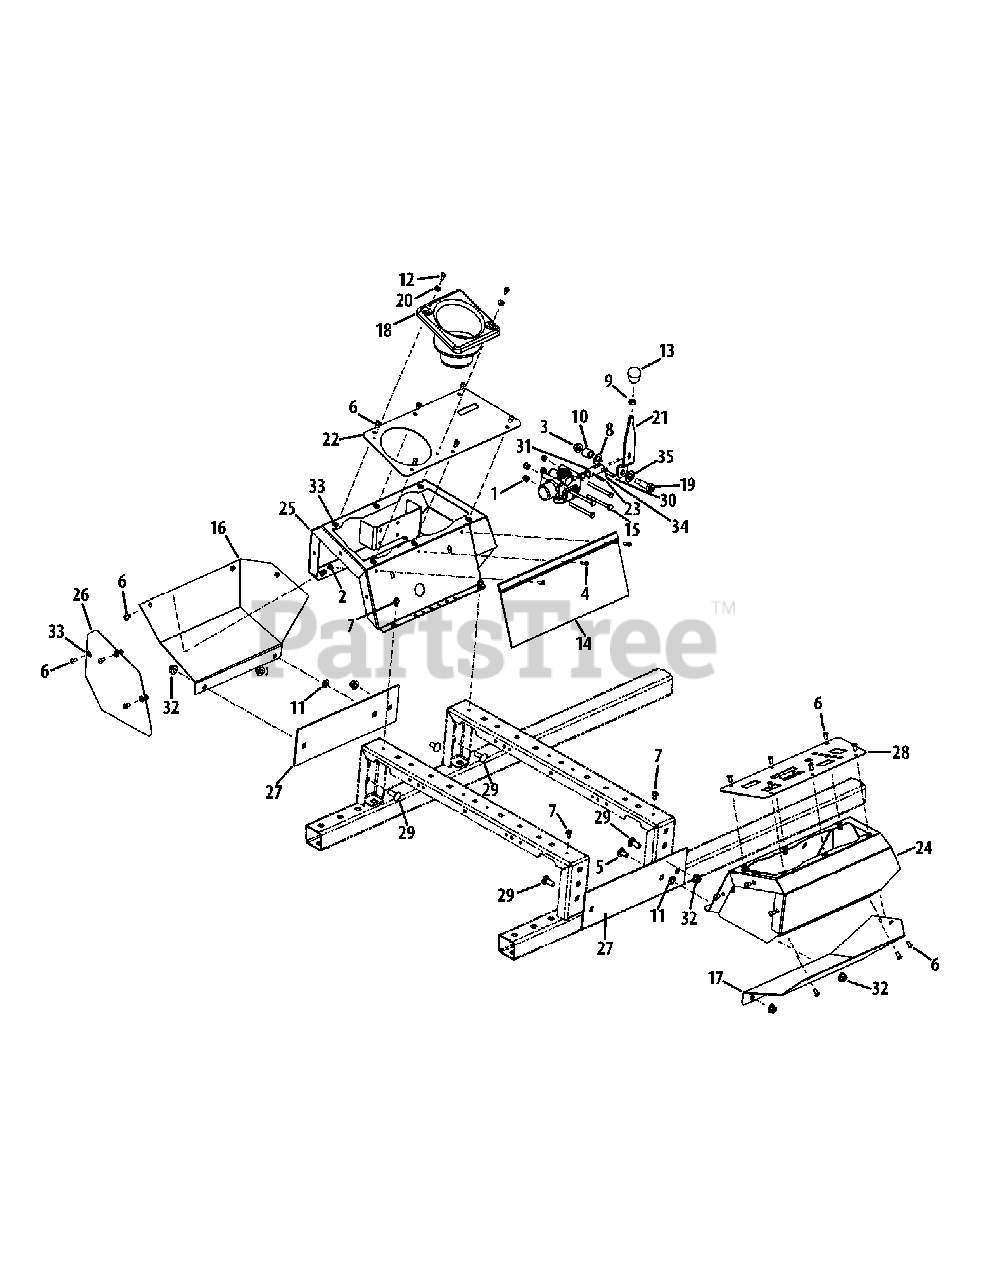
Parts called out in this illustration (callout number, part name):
1	Nylock Nut, 1/4-20
2	Nylock Nut, #10-32
3	Flange Counter Lock Nut, 3/8-16
4	Machine Screw, #10-32 x .625
5	Carriage Bolt, 3/8-16 x .75
6	Screw, 1/4-20 x .500
7	Hex Flange Screw, 1/4-20 x .500
8	Washer, .536 x .930 x .050
9	Jam Nut, 3/8-16
10	Spacer, .500 x .750 x .700
11	Push Nut, .335 x .780 x .015
12	Flange Screw, #10-32 x .500
13	Lever Knob, 3/8-16
14	Debris/Storage Bag
15	Hex Screw, 1/4-20 x 2.75
16	LH Lower Panel
17	RH Lower Panel
18	Cup Holder
19	Shoulder Bolt, 3/8-16 x .50 x 1.0
20	Washer, .300 x .550 x .047
21	Lift Valve Lever Bracket
22	LH Cover Control Panel
23	Spirol Pin, 3/16 x 1.0
24	LH Control Panel Assembly
25	RH Bracket Control Panel Assembly
27	Lower Side Panel
28	RH Cover Control Panel
29	Carriage Bolt, 3/8-16 x 1.00
30	Pin, .25 x .9375
31	Valve Link
32	Flange Lock Nut, 3/8-16
33	Rivet Nut, 1/4-20
34	Cotter Pin, 1/16 x .75
35	Bell Washer, .525 x 1.00 x .050
